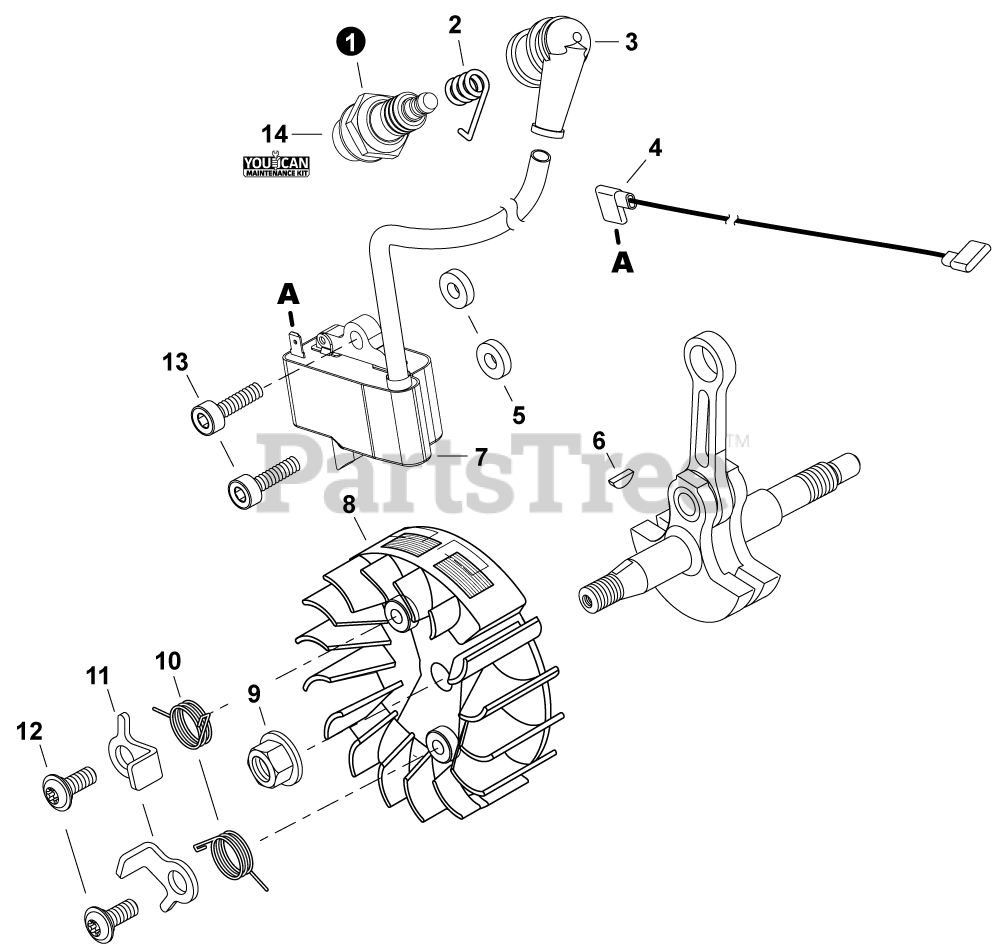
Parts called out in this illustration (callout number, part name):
1	SPARK PLUG - BPMR8Y
2	TERMINAL, SPARK PLUG
3	CAP, SPARK PLUG
5	WASHER 5.2x12x3
6	KEY, WOODRUFF
7	COIL, IGNITION
8	FLYWHEEL
9	NUT, FLANGE M8
10	SPRING, TORSION
12	BOLT 5x11
13	BOLT, TORX 5x20
14	TUNE-UP KIT - YOUCANT
